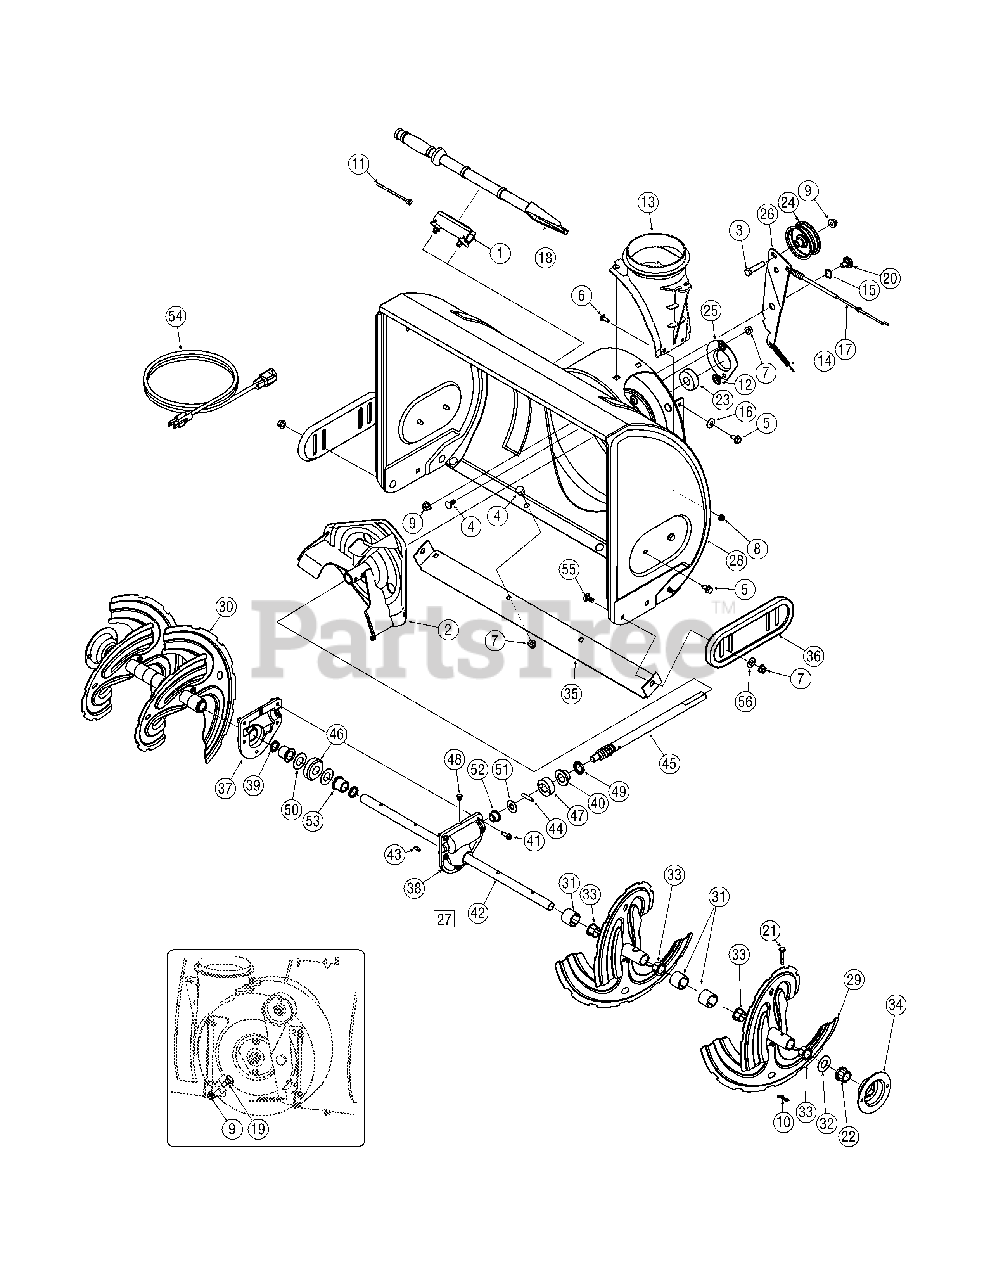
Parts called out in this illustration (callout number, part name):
1	Snow Removal Tool Mount
2	Impeller Assembly, 12" Dia.
3	Hex Screw, 3/8-16, 1.75, Gr5
4	Bolt, Carriage, 5/16-18, .750 Gr1
5	Screw, 5/16-18, 0.750
6	Screw, Carriage, 1/4-20, .750, Gr5
7	Nut, Flange Lock, 5/16-18, Nylon
8	Nut, Flange Lock, 1/4-20, Nylon
9	Nut, Flange Lock, 3/8-16, Nylon
10	Cotter Pin, Bow-tie
11	Cable, Tie, 3/16 x .05 x 7.4
12	Nut, Push-on, .25 Dia
13	Chute, Adapter 5" Dia
14	Spring, Extension, .38 OD x 4.59
15	Washer, Wave, .625 x .885 x .015
16	Washer, Bell, .340 x .872 x .060
17	Clutch Cable, Auger, 47.23"
18	Snow Removal Tool
19	Screw, Shoulder, .498 x .34, 3/8-
20	Screw, Shoulder, .625 x .17, 3/8-16
21	Shear Pin, .25 x 1.50
22	Bearing, Hex Flange x .75 ID
23	Bearing, Ball, .75 ID x 1.85 OD
24	Flat Pulley, Idler, 2.75 OD
25	Housing, Bearing, 1.85 ID
26	Bracket, Auger Idler w/ Brake
27	Gearbox Assembly, Auger, 26"
28	Housing Assembly, Auger 26"
29	Spiral Assembly, LH
30	Spiral Assembly, RH
31	Spacer, 1.25 OD x .75 ID x 1.00
32	Washer, Flat, .76 x 1.49 x .06
33	Bushing, Flange, .80 ID x .91 OD
34	Housing, 1" Hex Bearing
35	Shave Plate, 2.25 x 25.66
36	Slide Shoe
37	Housing, Auger, RH Reduced
38	Housing, Auger, LH Reduced
39	Seal, Oil, .750 x 1.00 x .125
40	Bearing, Flange, .75 x 1.0 x .59
41	Screw, Self-tapping, 1/4-20, 0.750
42	Axle, Auger, 26"
43	Key, Hi-pro 3/16 x 5/8
44	Pin, Dowel, .25 OD x 1.2
45	Shaft, Worm .75 OD
46	Gear, Worm 20T
47	Collar, Thrust
48	Plug, 1/4 x .437
49	Seal, Oil, .75 x 1 x .131
50	Washer, Flat, .760 ID x 1.5 OD
51	Washer, Flat, .51 x 1.12
52	Bearing, Flange, .75 x 1.0 x .925
53	Bearing, Flange, .75 x 1.00 x .975
54	Extension Cord, 110V
55	Screw, Carriage, 5/16-18 x 1.00
56	Washer, Flat, .349 x .879 x .063
